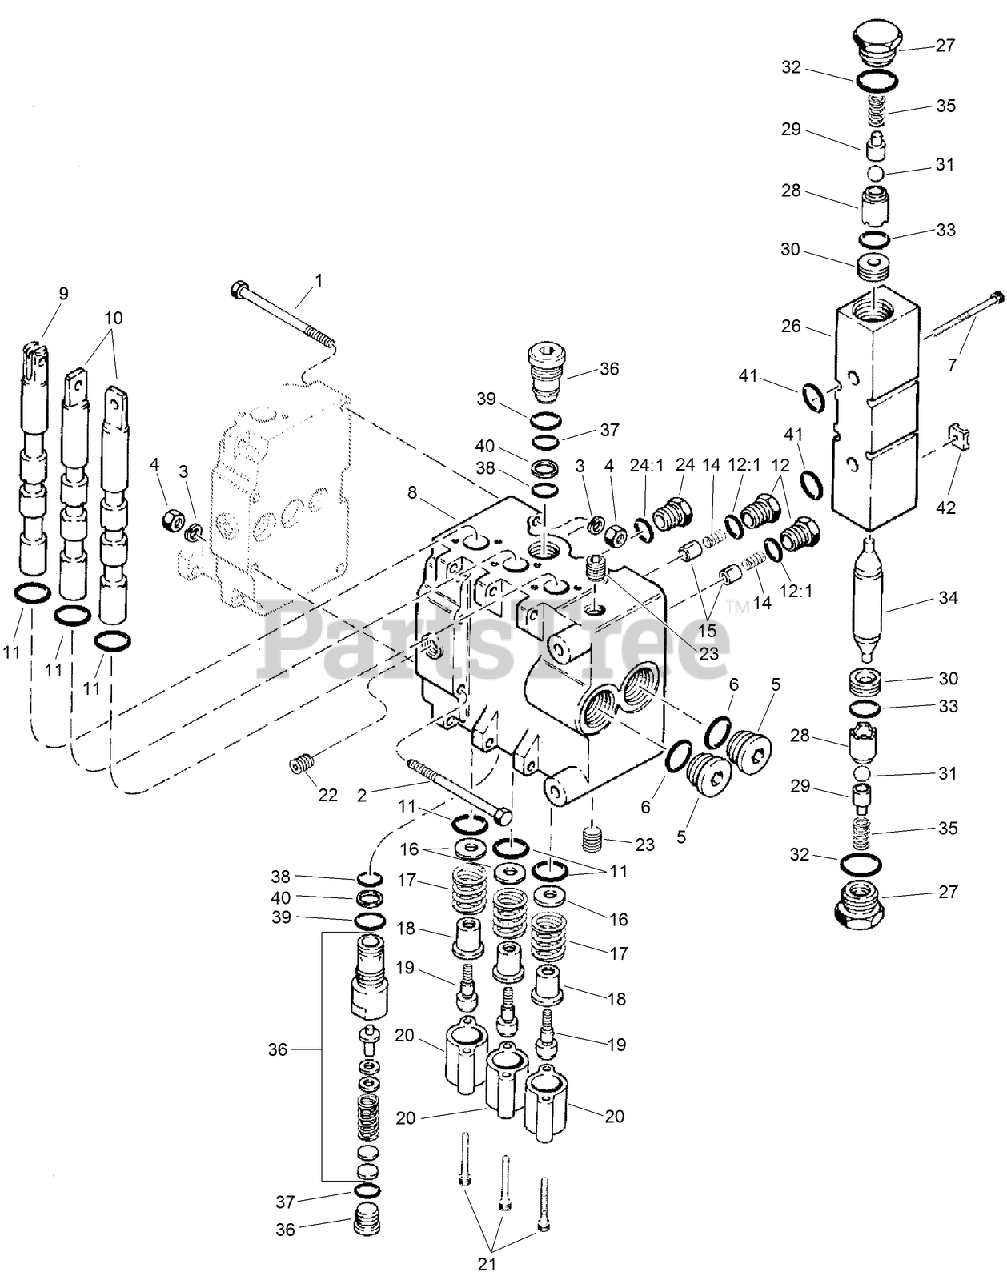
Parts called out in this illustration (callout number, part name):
1	SCREW-CAP
2	SCREW-HH
3	WASHER-FLAT
5	PLUG-SOCKET HEAD
6	O-RING
8	BODY-SECTION, OUTLET
9	SPOOL-STABLILIZER
10	SPOOL-CONTROL, DUAL
12	PLUG ASM
14	SPRING-poppet
15	POPPET-CHECK, LOAD
16	WASHER-FLAT
17	SPRING-RETURN
18	SPACER-spring
19	BOLT-SHOULDER
20	Cap-End
22	PLUG-seal
23	PLUG
24	PLUG ASM
26	BODY-CHECK, PILOT
27	PLUG-CHECK, PILOT
28	SLEEVE-CHECK, PILOT
29	RETAINER-ball
30	SEAT-CHECK, PILOT
31	BALL-CHECK, PILOT
32	O-RING
33	O-RING
34	PLUNGER-CHECK, PILOT
35	SPRING-CHECK, PILOT
36	Valve-Relief
39	O-RING
40	RING-BACKUP
42	ORIFICE
